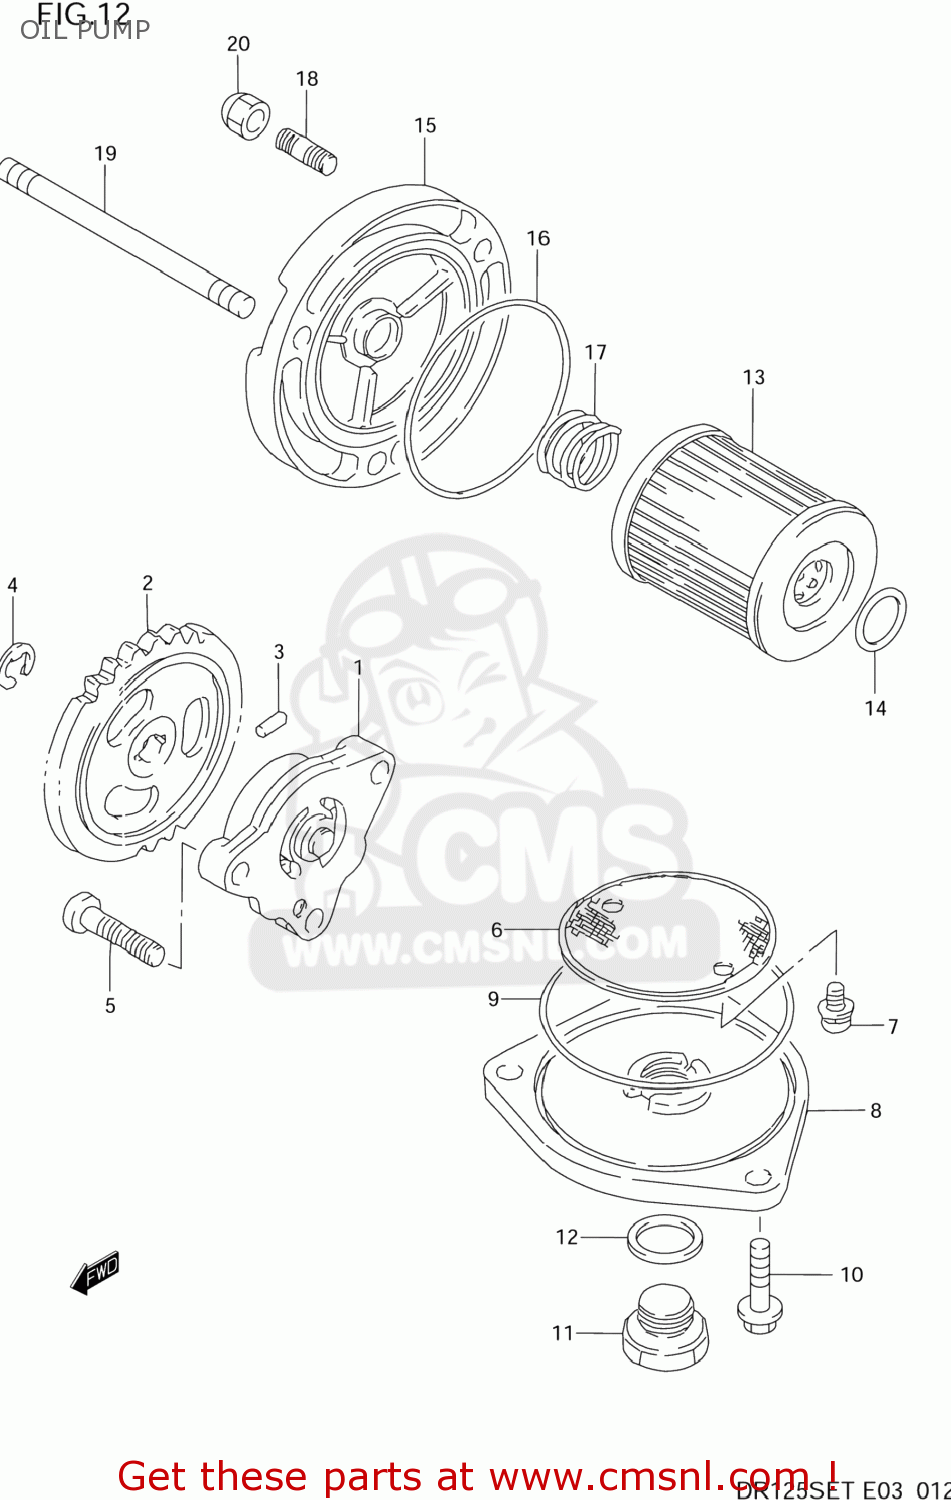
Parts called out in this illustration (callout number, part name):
1	PUMP ASSY,ENGINE OIL
2	GEAR,OIL PUMP DRIVEN (N
3	PIN(2.5X11.8)
4	E.RING
5	SCREW
6	STRAINER,ENGINE OIL
7	SCREW
8	CAP,OIL STRAINER
9	O RING(D:2.4,ID:60.5)
10	SCREW
11	PLUG
12	GASKET(13.8X18.8X4.8) (NAS)
13	FILTER,OIL
14	O RING(D:1.9,ID:13)
15	CAP,OIL FILTER
16	O RING(D:2.4,ID:52.6)
17	SPRING
18	STUD 6X12
19	BOLT,STUD
20	NUT
